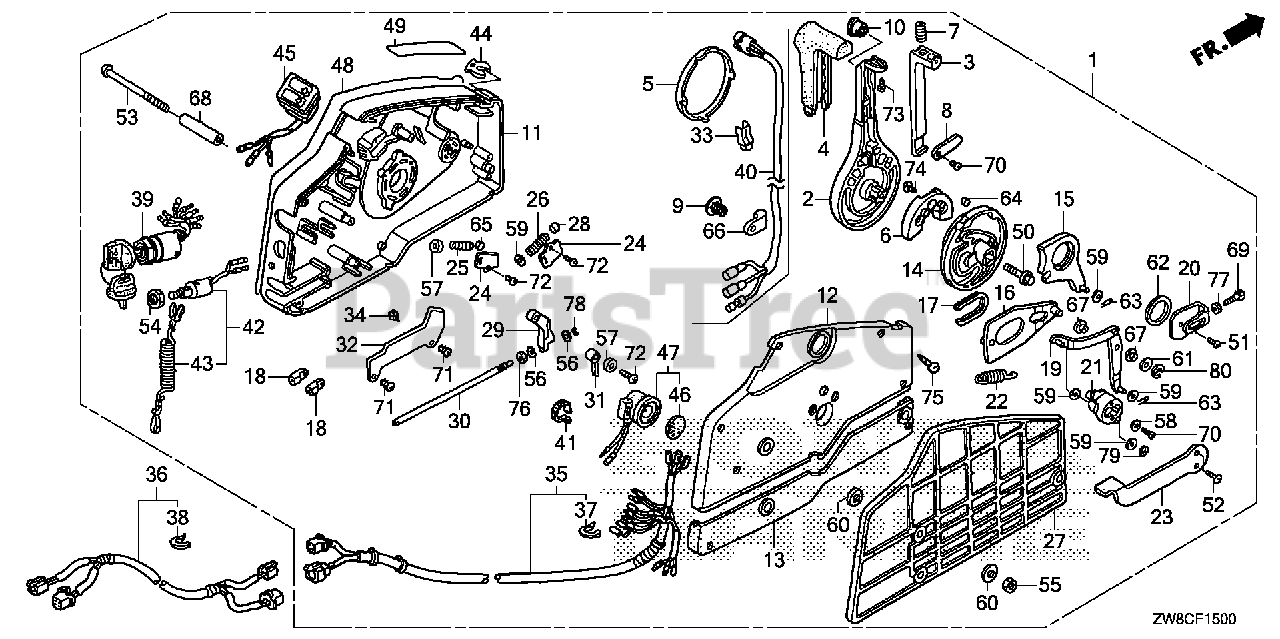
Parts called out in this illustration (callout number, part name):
1	S/R SW 2 LIGH MAN TL
1	BOX ASSY., REMOTE CONTROL (HI-LEX)
2	HANDLE, REMOTE CONTROL
3	LEVER, HANDLE LOCK
4	GRIP, REMOTE CONTROL HANDLE
5	CAP, HANDLE
6	BLOCK, NEUTRAL LOCK
7	SPRING, REMOTE CONTROL HANDLE
8	PLATE, LEVER SETTING
10	COVER, GRIP
11	HOUSING, REMOTE CONTROL BOX (A)
12	HOUSING, REMOTE CONTROL BOX (B)
13	HOUSING, REMOTE CONTROL BOX (C)
14	WHEEL, CONTROL
15	ARM, SHIFT LINK
16	PLATE, SLIDING
17	COLLAR, SLIDING PLATE
18	PIVOT, SHIFT
19	ARM, LINK JOINT
20	BRACKET, LINK JOINT
21	WHEEL, ACCELERATOR
22	SPRING, ACCELERATOR WHEEL
23	LEVER, IDLE
24	PLATE, SPRING SETTING
25	SPRING, SHIFT CLICK
26	SPRING, CHOKE RETURN
27	SPACER, REMOTE CONTROL BOX
28	SPACER, CLICK SPRING
29	BLOCK, THROTTLE FRICTION
30	BOLT, FRICTION
31	SPACER, NEUTRAL SWITCH
34	SPACER, CABLE CLAMP
35	CABLE ASSY. B, REMOTE CONTROL (4P+6P)
36	CABLE ASSY., REMOTE CONTROL EXTENSION (4P+4P)
36	CABLE ASSY., REMOTE CONTROL EXTENSION (4P+6P)
37	TIE, CABLE (2.4X92) (NATURAL)
38	TIE, CABLE (2.4X92) (NATURAL)
39	SWITCH ASSY., COMBINATION
41	BAND (BLACK 3.5X140)
42	SWITCH ASSY., EMERGENCY STOP
43	WIRE, EMERGENCY
44	CLIP, EMERGENCY LOCK
45	LAMP ASSY., INDICATOR
46	PLATE, TURN SIGNAL BUZZER
47	BUZZER, WARNING
48	PLATE, REMOTE CONTROL (COUTION COLOR=RED & YELLOW)
49	MARK, FAST IDLE
50	BOLT, FLANGE (8X35)
51	SCREW, PAN (6X10)
52	SCREW, FLAT (5X12)
53	SCREW (6X95)
54	NUT, HEX. (16MM)
55	NUT, HEX. (6MM)
56	WASHER, PLAIN (4MM)
57	WASHER, PLAIN (5MM)
58	WASHER, PLAIN (5MM)
59	WASHER, PLAIN (6MM)
60	WASHER (6MM)
61	WASHER, PLAIN (8MM)
62	WASHER (28MM)
63	PIN, LOCK (6MM)
64	PIN (6X6)
65	ROLLER, CLICK
67	COLLAR, LINK JOINT
68	COLLAR, DISTANCE (6X10X43.5)
69	BOLT, HEX. (5X16)
70	SCREW, PAN (5X10)
72	SCREW, TAPPING (5X10)
73	SCREW, TAPPING (5X12)
74	SCREW, TAPPING (6X16)
75	SCREW, TAPPING (5X25)
76	NUT, HEX. (6MM)
77	NUT, HEX. (5MM)
78	E-RING (3MM)
79	E-RING (4MM)
80	E-RING (7MM)
